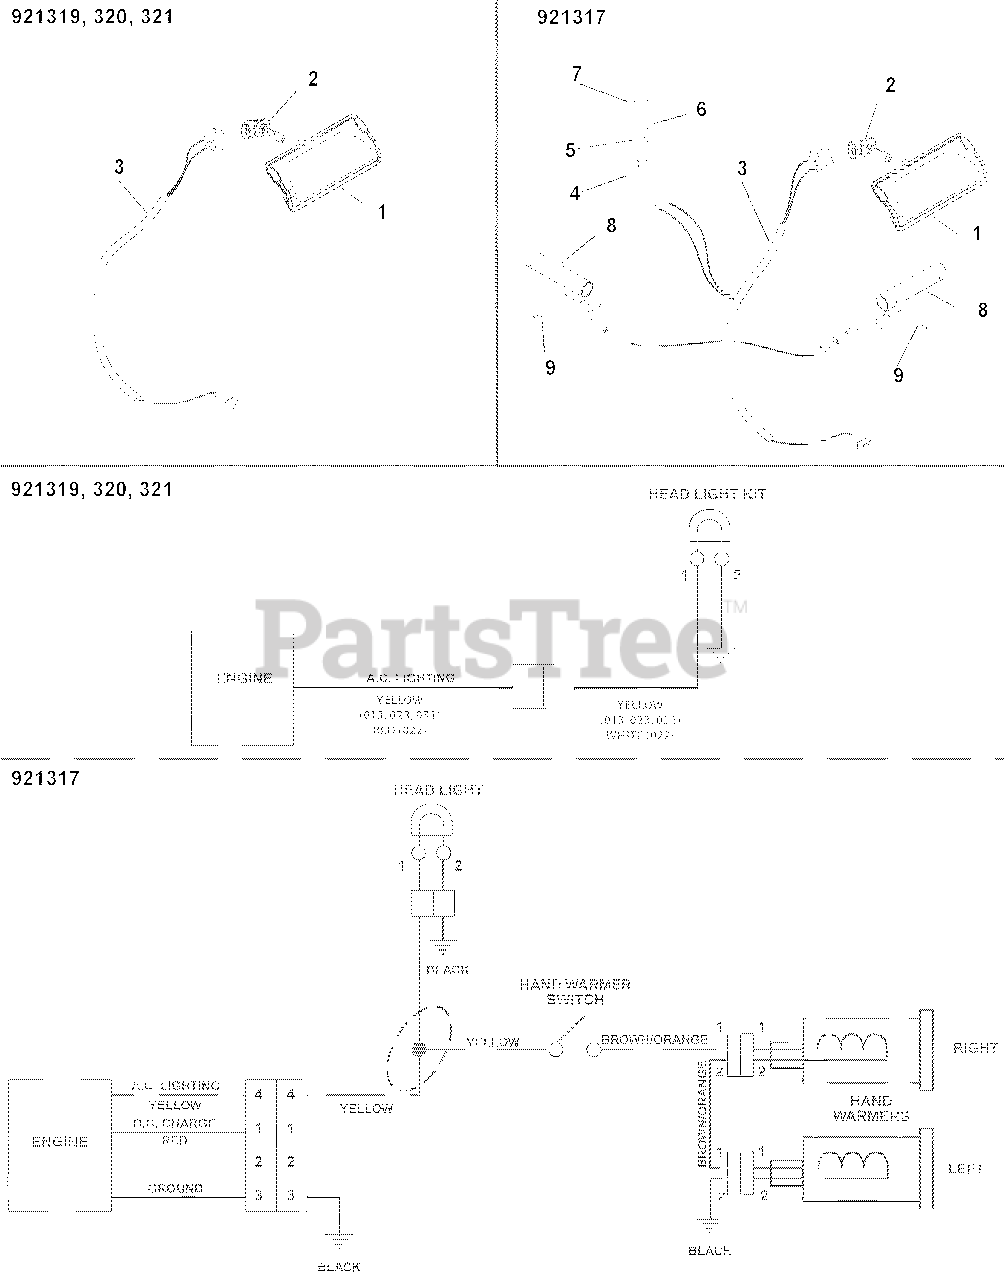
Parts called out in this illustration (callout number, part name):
1	HEADLIGHT ASY, HALO 20W 2SHOT
2	BULB, LIGHT-HALOGEN 20W
3	HARNESS, LIGHT & WARMER
3	HARNESS, LIGHT - DELUXE
4	SWITCH, ON/OFF
5	WSHR-LK-INT .563X.040 YWZC
6	WSHR-FL-STL .505X.875X.024 PL
7	BOOT, SWITCH
8	HEATED GRIP, MAGURA
9	RVT-POP #43 .125X.313 STL ZINC
